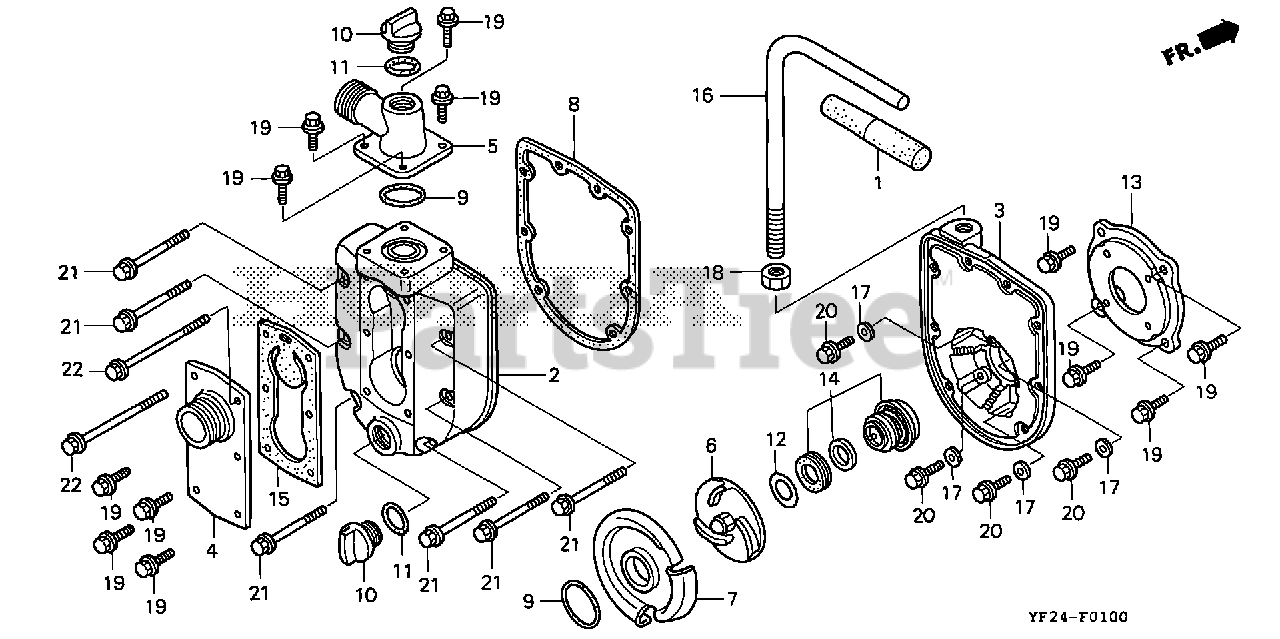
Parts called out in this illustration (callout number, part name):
1	GRIP, FR. CLUTCH LEVER
2	CASING
3	PLATE, END
4	PLATE, SUCTION (NPT)
5	PIPE, OUTLET (NPT)
6	IMPELLER
7	CASE, VOLUTE
8	GASKET, END PLATE
9	RING A, SEAL
10	CAP, FILLER
11	RING, SEAL (B)
12	SHIM, ADJUSTER
13	CASE, SPACER
14	SEAL ASSY., MECHANICAL
15	GASKET, SUCTION
17	WASHER, SEALING (6MM)
18	NUT, HEX. (12MM)
19	BOLT, FLANGE (6X16)
20	BOLT, FLANGE (6X18)
21	BOLT, FLANGE (6X55)
22	BOLT, FLANGE (6X85)
